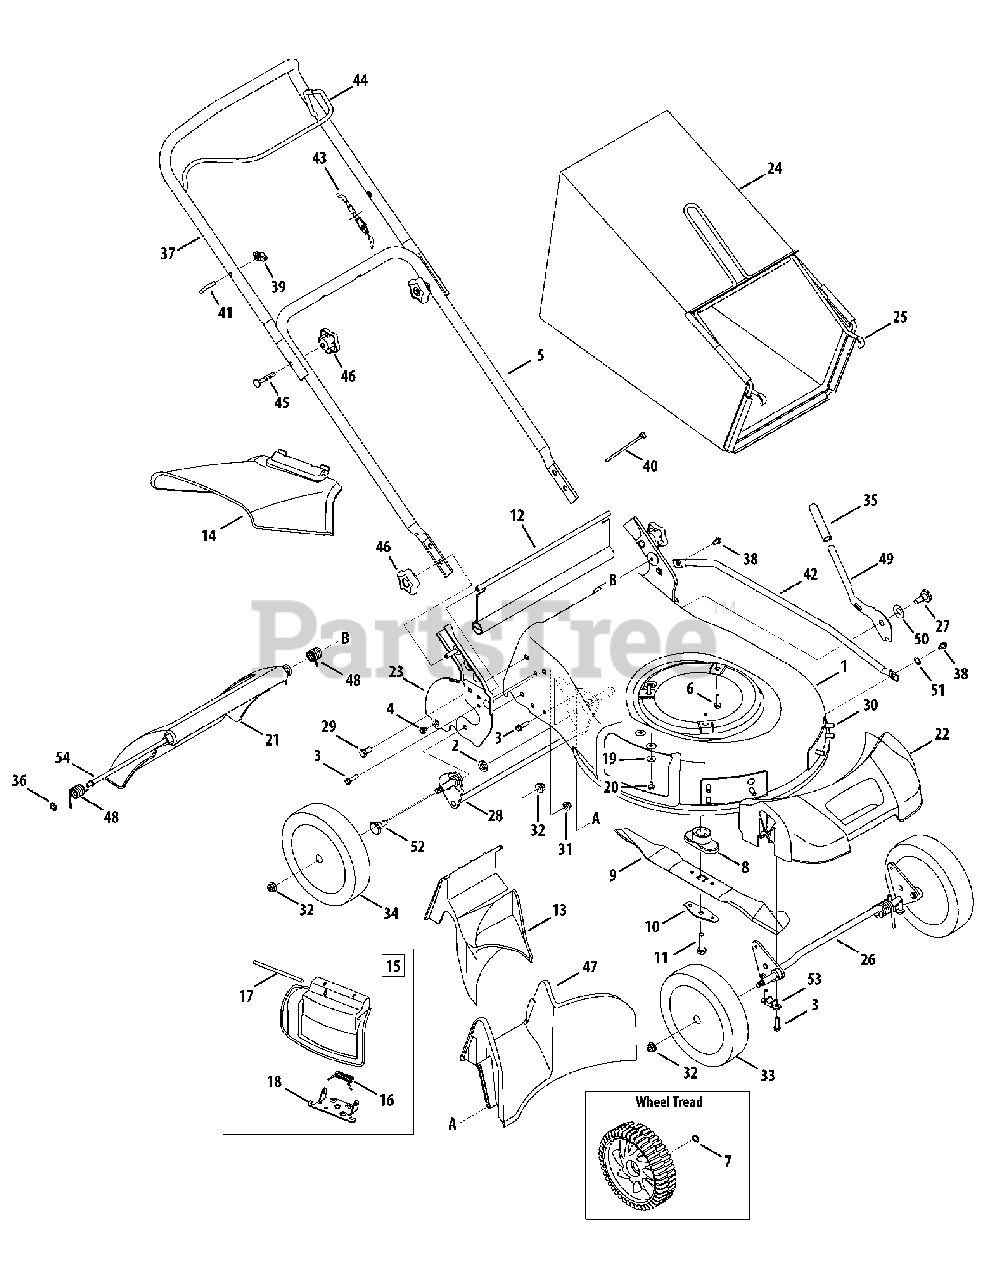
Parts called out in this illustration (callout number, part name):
3	Screw, 1/4-15 x 1.000
4	Screw, #10-16 x .500
6	Screw, tt, 3/8-16 x 1.00
7	Washer, Wave, .510 x .750 x .017
8	Blade Adapter
9	Mulching Blade
10	Blade Bell Support
11	Screw, 3/8-24 x 1.50
12	Trailing Shield
13	Rear Mulch Plug
14	Side Discharge Chute
15	Mulch Plug
16	Torsion Spring
17	Hinge Pin
18	Chute Deector Adapter
19	Beleville Washer
21	Rear Door
22	Front Cover
24	Grass Bag
27	Screw, Shoulder, .50 x .66
29	Hhcs, 5/16-18 x .625
30	Screw, 5/16-14 x .750
31	Nut, Flange Lock, 5/16-18
32	Nut, Flange Lock, 3/8-16
33	Front Wheel
34	Rear Wheel
35	Foam Grip
36	Nut, Spd.
38	Screw, 1/4-20 x .50
40	Cable Tie
41	Rope Guide
43	Control Cable
44	Blade Control
45	Bolt Carriage, 5/16-18 x 2.0
46	Star Knob
47	Rear Baffle
48	Door Torsion Spring - RH
48	Door Torsion Spring - LH
49	Spring Lever
50	Washer, Bell, .510 x 1.14 x .040
51	Washer, Wave, .390 x .825 x .016
52	Screw, Shoulder, .500 Dia. X .434
53	Bushing, Lock, .505 Dia. X .62
54	Rear Door Pivot Rod
